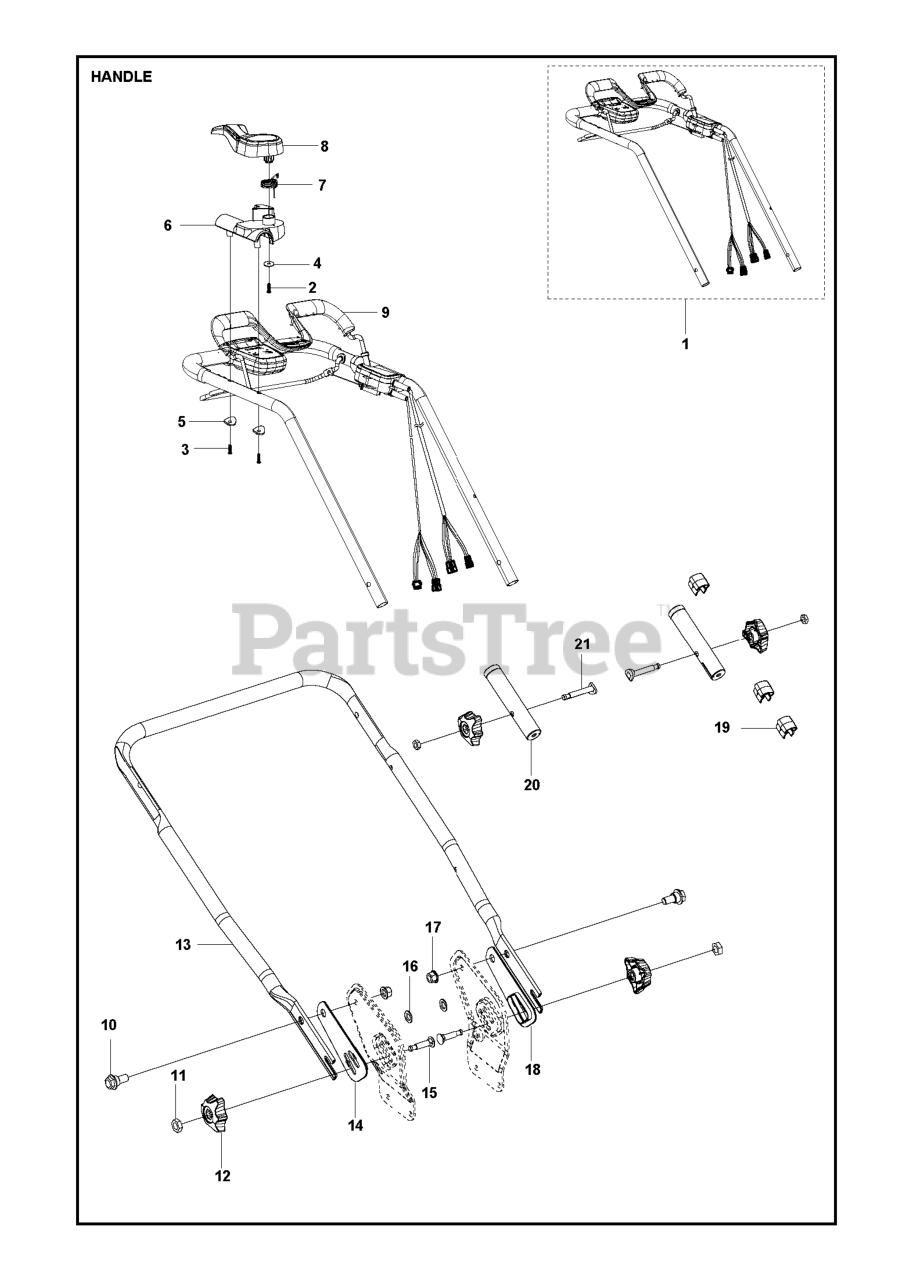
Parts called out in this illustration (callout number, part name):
1	RP STARTER ASSY
1	HANDLE KIT DAYE# 90000305301
3	SPACING SLEEVE
4	STARTER ROPE
5	STARTER HANDLE
6	HOLDER BAIL STOP SOLUTION HOLD
7	DRIVER PULLEY
7	TORSION SPRING
8	SPRING - DRIVER
8	COVER BAIL STOP SOLUTION
9	STARTER PULLEY
9	COVER BAIL ARM COVER
10	STARTER PULLEY
11	HEXAGON NUT #26800502301
12	RP STARTER HOUSING
12	KNOB #25341500101
13	SPACING SLEEVE
13	HANDLEBAR LOWER
14	STARTER PAWL BRIDGE
14	PLATE RIGHT
16	SPACER RING
17	STARTER PAWL
17	LOCKING BOLT M8,GB6187.1 #2680
18	DECAL, STARTER HOUSING
18	DECAL DEVICE
18	PLATE LEFT
19	PLATE
19	HOLDER CABLE
22	SCREW
